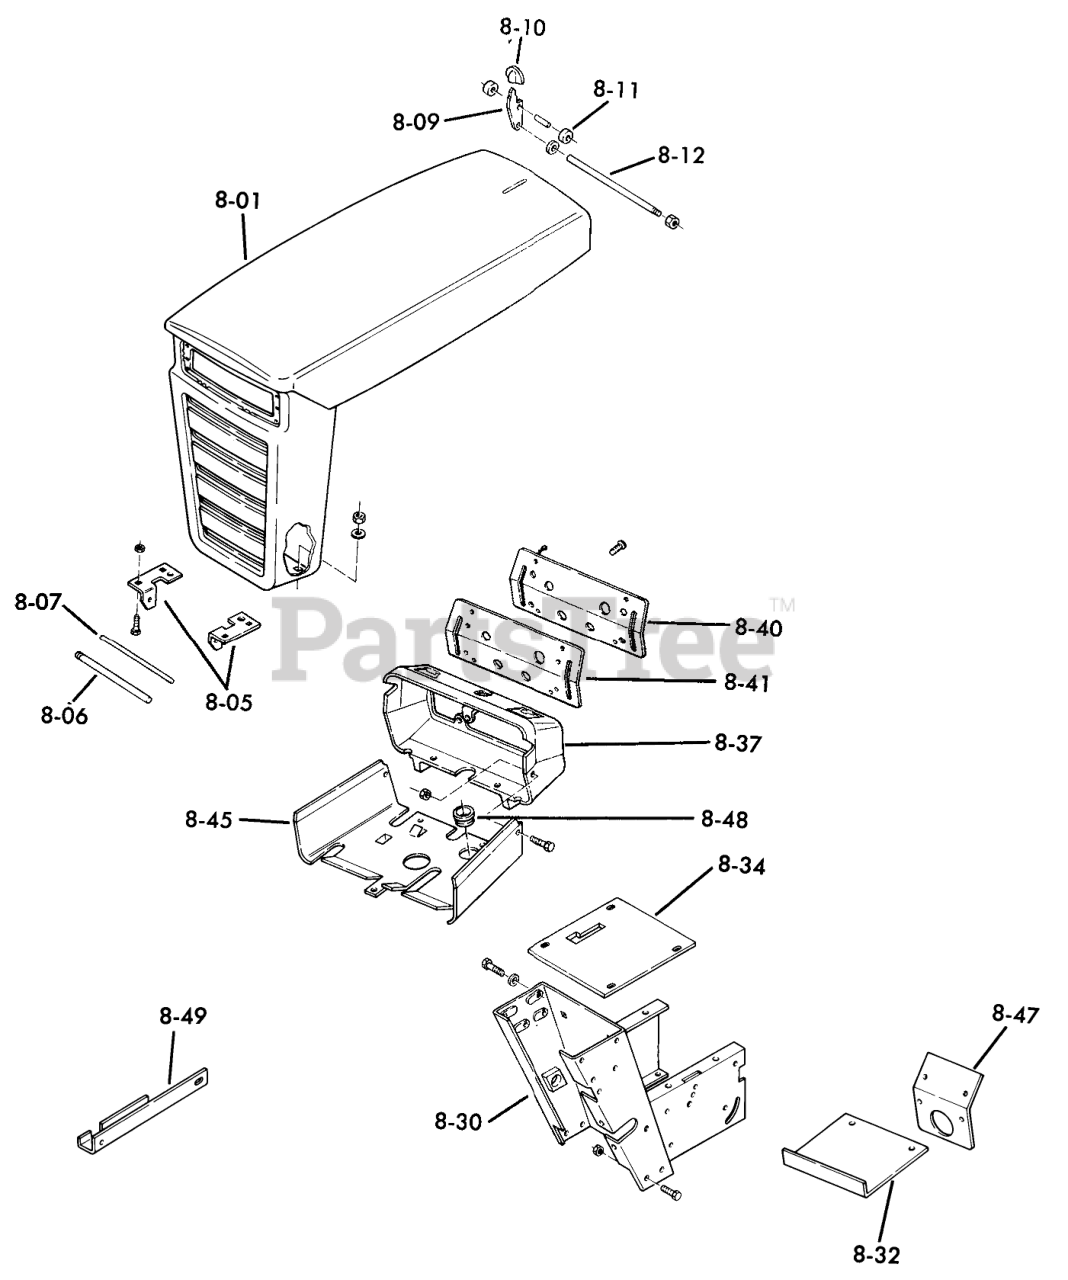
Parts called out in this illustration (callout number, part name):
8-01	Hood
8-05	GRILL PIVOT BRKT
8-06	GRILL PIVOT ROD
8-07	ROD-HOOD STOP
8-09	LEVER HOOD LATCH
8-10	KNOB
8-11	Roller
8-12	Rod Latch
8-30	Assy-Hoodstand
8-32	Cover-Dust
8-34	Cover Plate
8-37	Housing
8-40	Dash Panel
8-41	BACK UP PLATE
8-45	Support-Tank
8-47	Instrument Backet
8-48	Grommet
